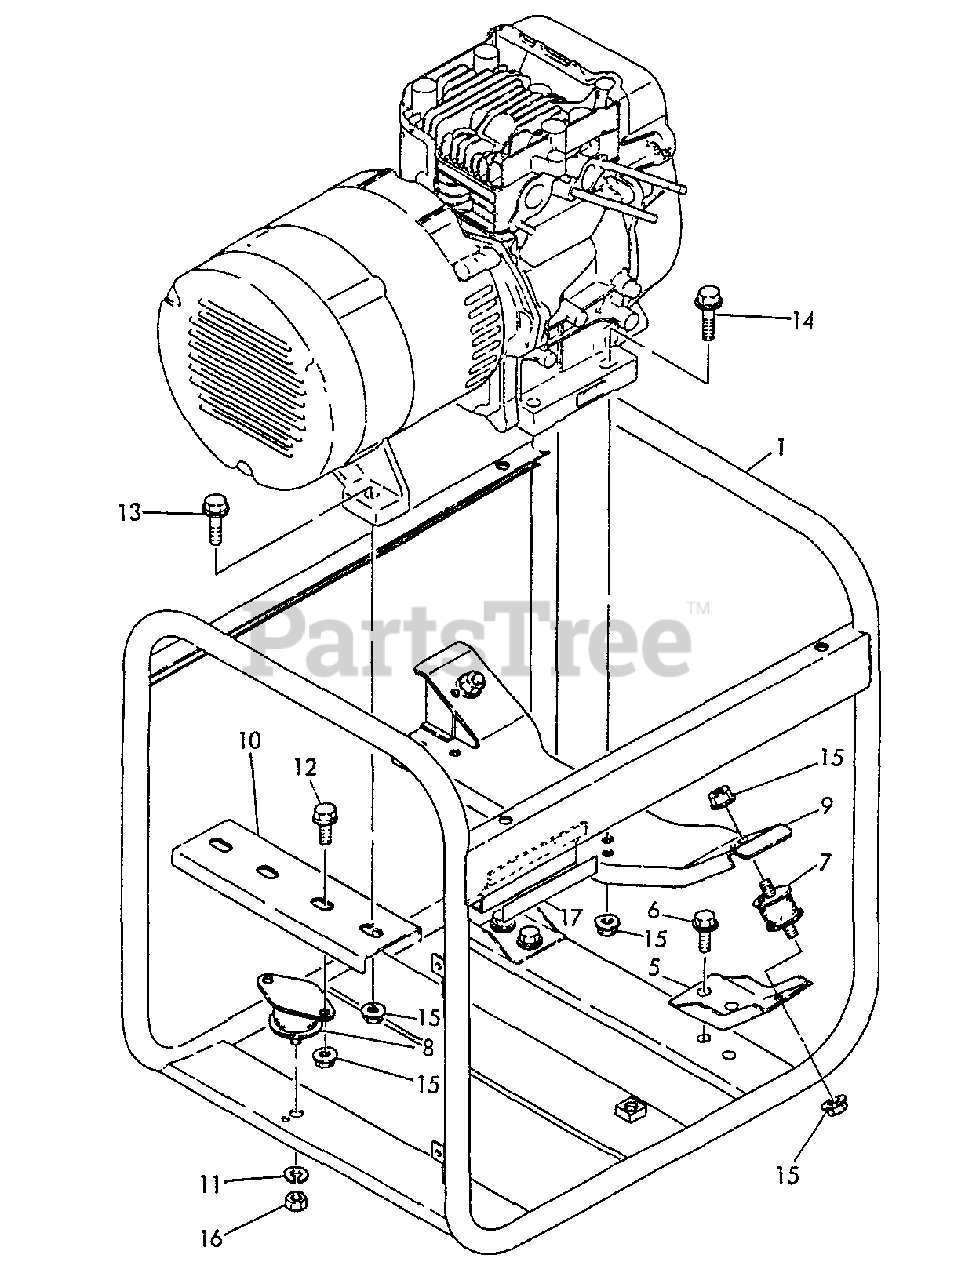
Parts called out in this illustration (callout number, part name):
1	FRAME ASSY
5	DAMPER STAY, LOWER
6	BOLT - 8X16 -- PLATED
7	DAMPER, FRONT
8	DAMPER, REAR
9	STAY, DAMPER
10	STAY, REAR DAMPER
11	LOCKWASHER - 10
12	BOLT - 8X20 -- PLATED
13	BOLT - 8X30 -- PLATED
14	BOLT - 8X38 -- PLATED
15	NUT - 8
16	NUT - 10
17	SHEET, FRAME
